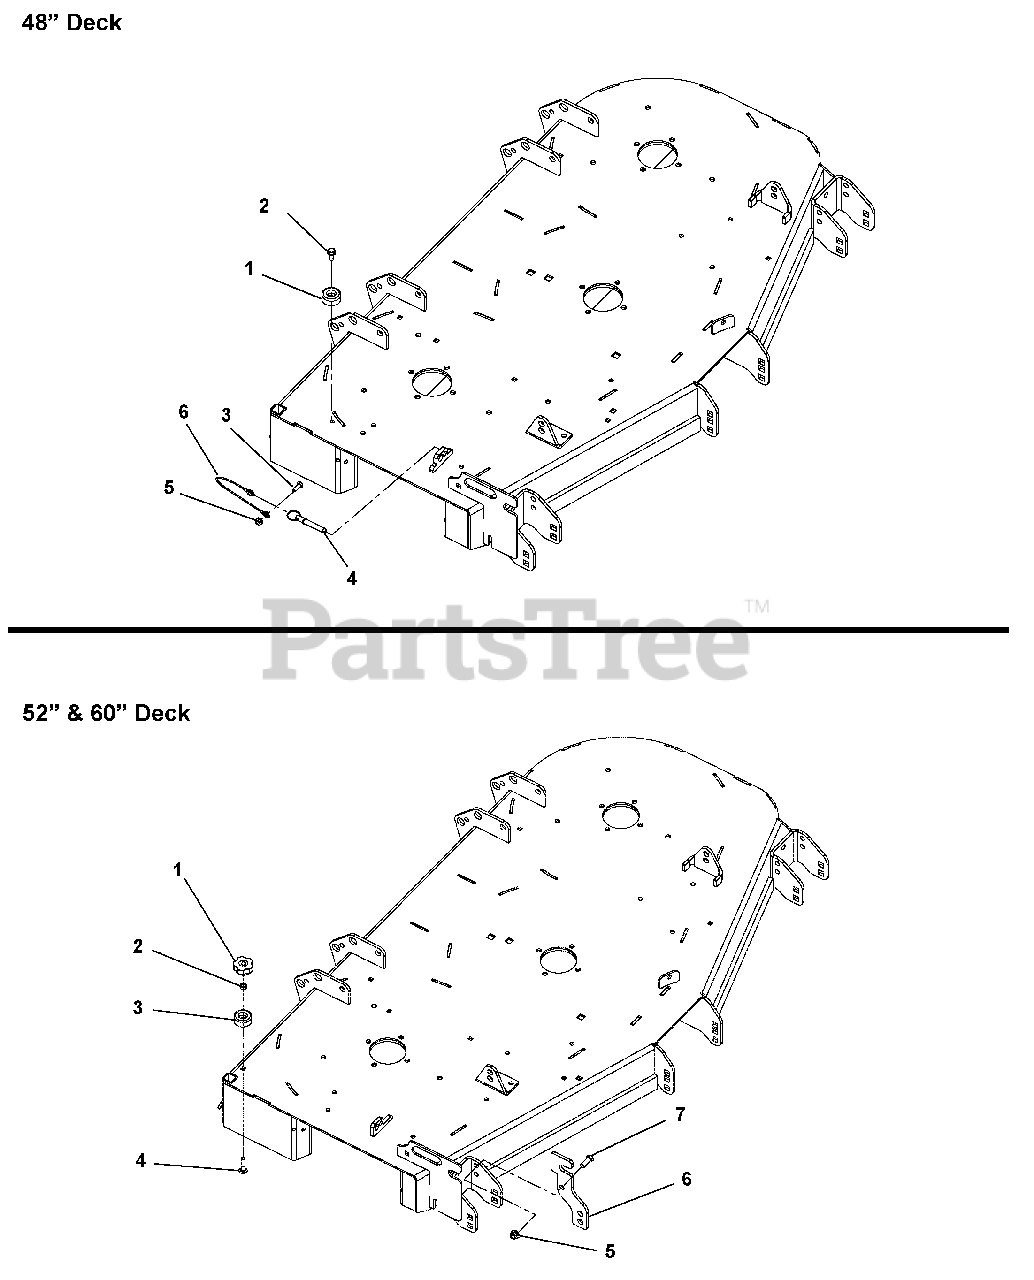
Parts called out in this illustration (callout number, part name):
1	KNOB-CLAMPING, .312-18 NYLOC
2	NUT-LK-CTR .31-18 YWZC
3	BUMPER,RECESSED1.50X.63 W/.31
4	BLT-RDHDSQNK .31-18X1.50 G5YZ
5	NUT-LK-NYL-FLG .38-16 YWZC
6	CHUTE STORAGE BRACKET - RED
7	BLT-HEX .38-16X1.00 GR5 YWZC
